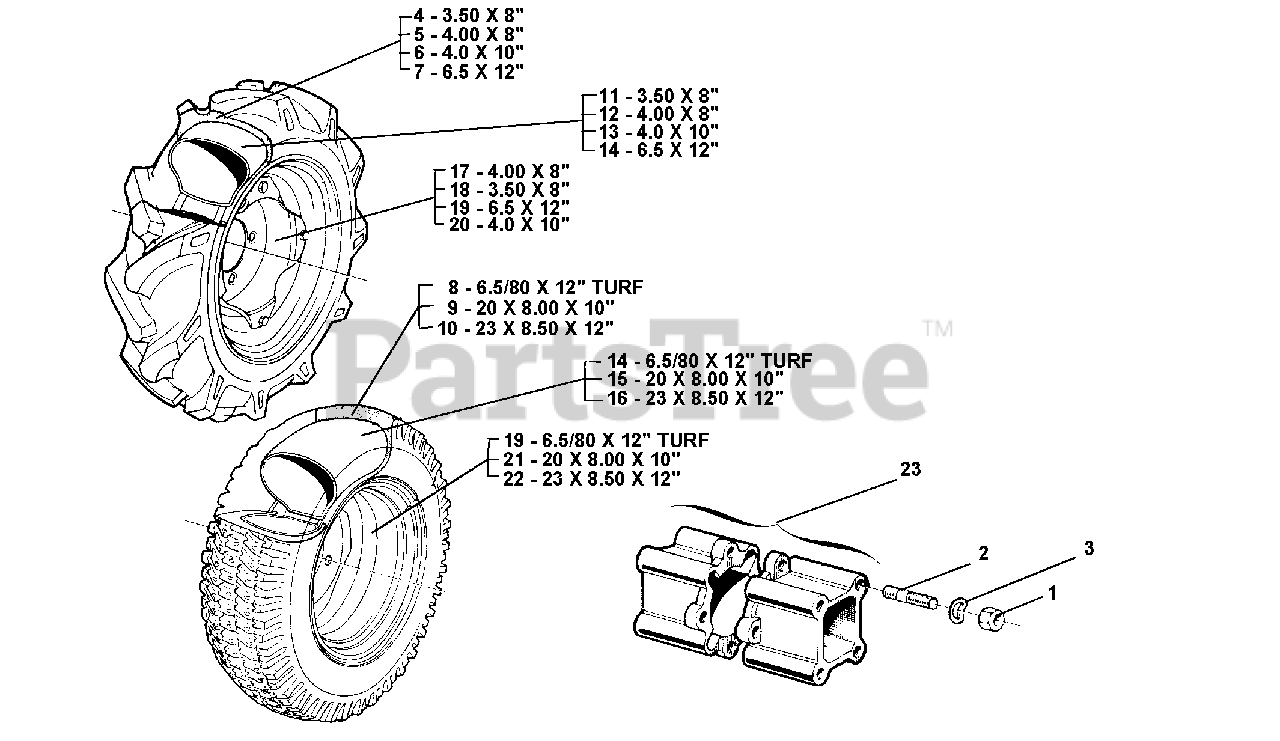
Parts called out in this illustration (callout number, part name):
2	STUD M10 X 40 X 22 X 14
3	WASHER, LOCK 10.5
4	TIRE 3.50 8 TRAC.
5	TIRE TRACTOR 4.00 X 8
6	TIRE TRACTOR 4.0 X 10
7	TIRE 6.5 X 12
8	TIRE 6.50/80 X 12
9	TIRE 20 X 8.00 X 10
10	TIRE 23 X 8.50 X 12
11	TUBE 3.50 8P
12	TUBE 4.00 X 8
13	TUBE 4.0 X 10
14	TUBE 6.5 X 12
15	TUBE 20 X 8.00 X 10
16	TUBE 23 X 8.50 X 12
17	WHEEL, DISK, 2.50 X 8
18	RIM 2.50 X 8 FOR 601
19	RIM 5JA - 12 INCH. ADJ. TRACK
20	RIM 3.50 D 10 (INCH) C.VAR.COM.
21	RIM 6.00 1 - 10"
22	RIM 7.00 J - 12"
23	WHEEL SPACERS, 2.5" (PR)
